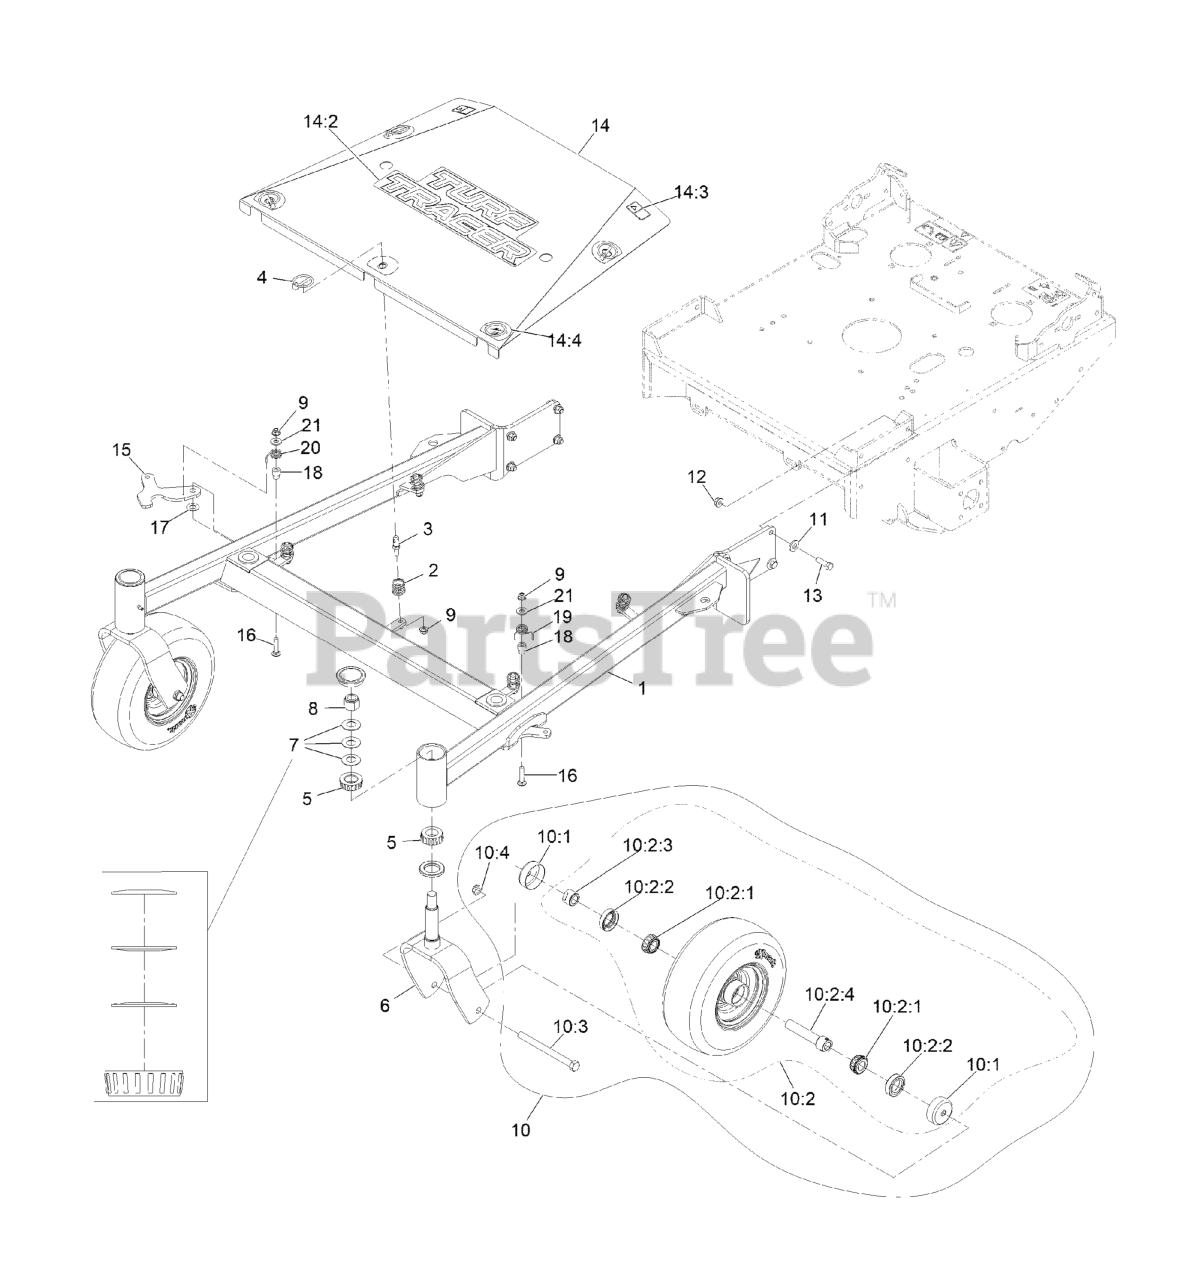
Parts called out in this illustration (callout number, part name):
1	ASM, FRONT FRAME W/ BEARINGS, 52
3	PIN, SPRING
4	PIN-LYNCH
5	Cone-Bearing Tapered Roller
6	WLD, CASTER FORK
7	WASHER-BELLVILLE
8	NUT-LOCK, NI
9	NUT-HF, NI
10	ASM,WHEEL&BEARINGS
10:1	GUARD-SEAL
10:2	Wheel And Bearing ASM
10:2:1	BEARING-CONE, TAPERED ROLLER
10:2:2	SEAL-CASTER
10:2:3	SPACER-NUT
10:2:4	CASTER AXLE ASM
10:3	SCREW-HH
10:4	NUT-HEX
11	WASHER-BELLEVILLE
12	NUT-HF, NI
13	SCREW-HH
14	ASM, CENTER SHIELD W/ DECALS, 52
14:2	DECAL-TURF TRACER
14:3	DECAL-WARNING
14:4	DECAL-SCRATCH COVER
15	LATCH, DECK HEIGHT
16	BOLT-CARR
17	Washer-Plastic
18	COLLAR-BASKET
19	SPRING-TORSION, LH (YELLOW)
20	Spring-Torsion, RH
21	WASHER-FLAT
